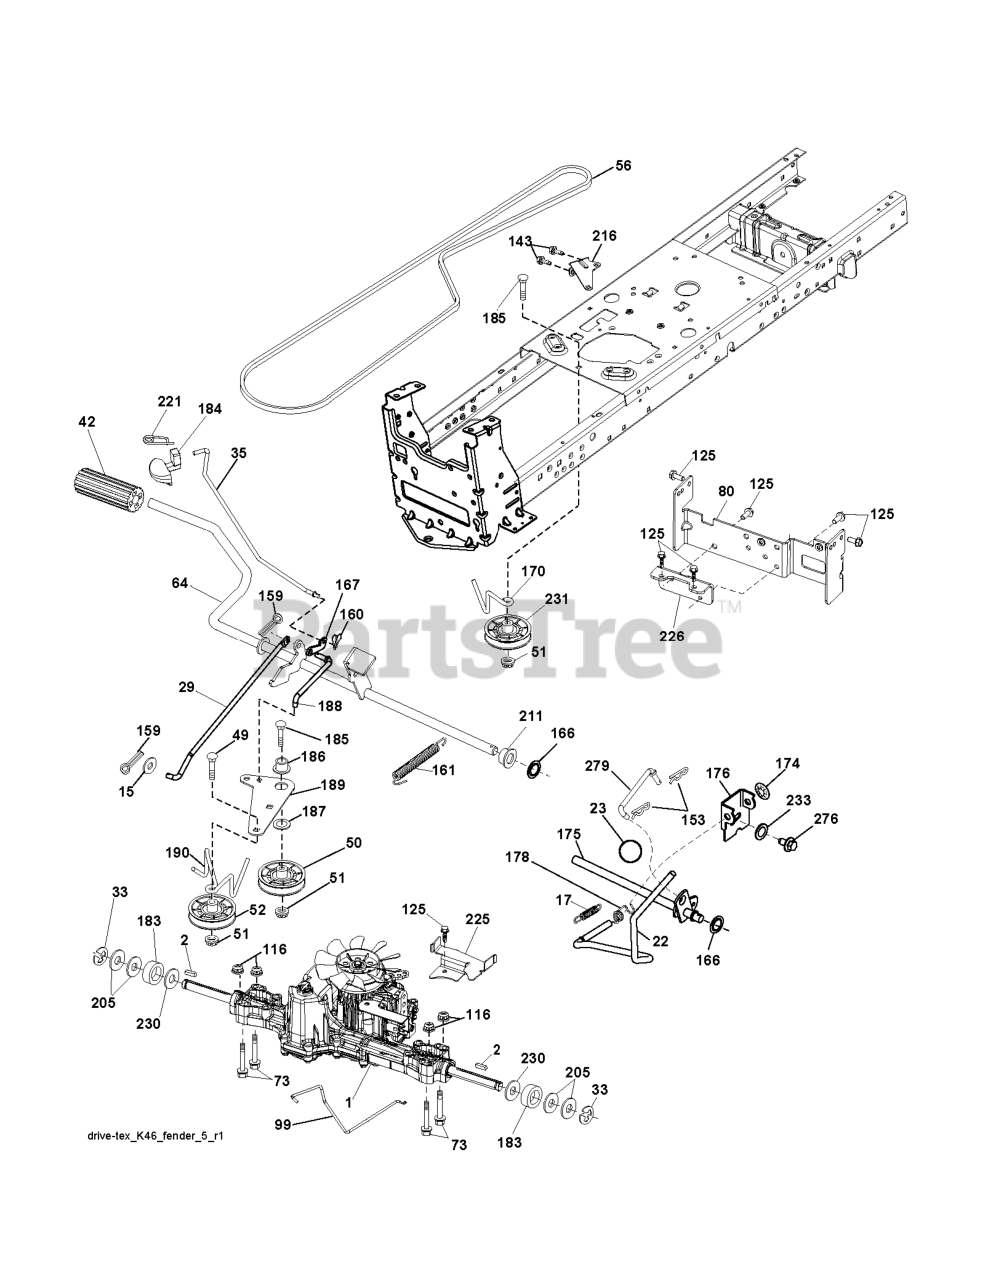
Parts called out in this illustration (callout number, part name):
2	SQUARE KEY
15	WASHER
17	SPRING.BRAKE.K46.GREEN
22	ROD.SHIFT.FENDER.TLT.2006
23	KNOB.DUCKHEAD.1/2
29	ROD.BRAKE.K46
35	ROD.CNTRL.PARK.PREDATOR.LT.TEX
42	PEDAL COVER T
50	IDLER.FLAT.910.OFFSET
51	NUT LOCK FLG 3/8-16 UNC
52	IDLER.V-GROOVE.910.OFFSET
56	V-BELT.MOWER.92.40.42/K46
64	SHAFT.ASM.PEDAL.BRAKE.
73	BOLT HEX 5/16-18 GR 5
80	STRAP TORQUE
99	ROD.SPRING.BYPASS.K46.LT.Z
116	NUT LOCK HEX FLANGE 5/16-18
125	SCREW
143	Screw 5/16-18 x 1/2 Hex, Self Tapping 5/16-18 x 1/2
153	RETAINER M
159	COTTER PIN
160	RETAINER CLIP
161	SPRING, RETURN LT
166	NUT.PUSH.625
167	LATCH.BRAKE.SPRING
170	KEEPER.CENTER SPAN.1.688
174	NUT.PUSH.500.2006
175	SHAFT.ASM.SHFT.T2.TLT
176	ARM.CLEVIS.ROD.SHIFT
178	SPRING.SHIFT.GT2006
183	SPACER AXLE
184	HANDLE PARKING BRAKE
186	SPACER.RETAINER
187	WASHER 12/32X2X10GA
188	RP.LINK.CLUTCH.GROUND.DRIVE
189	BELLCRANK.GROUND.DRIVE.TEX.
190	KEEPER.BELLCRANK.DRIVE
211	BUSHING.SHAFT.BRAKE.HAND
216	BRACKET.PULLEY.IDLER.W/TEX
221	RETAINER.SPRING.CLIP.H
225	KEEPER.BELT.TRANSAXLE.K46
226	BRACKET.MOUNT.TORQUE.K46.TLT
230	WASHER.HARDENED
231	IDLER.V-GROOVE.1.688.OFFSET
233	WASHER SERRATED
276	BOLT FIN HEX 7/16-14 X 1
279	LINK.SHIFT.
